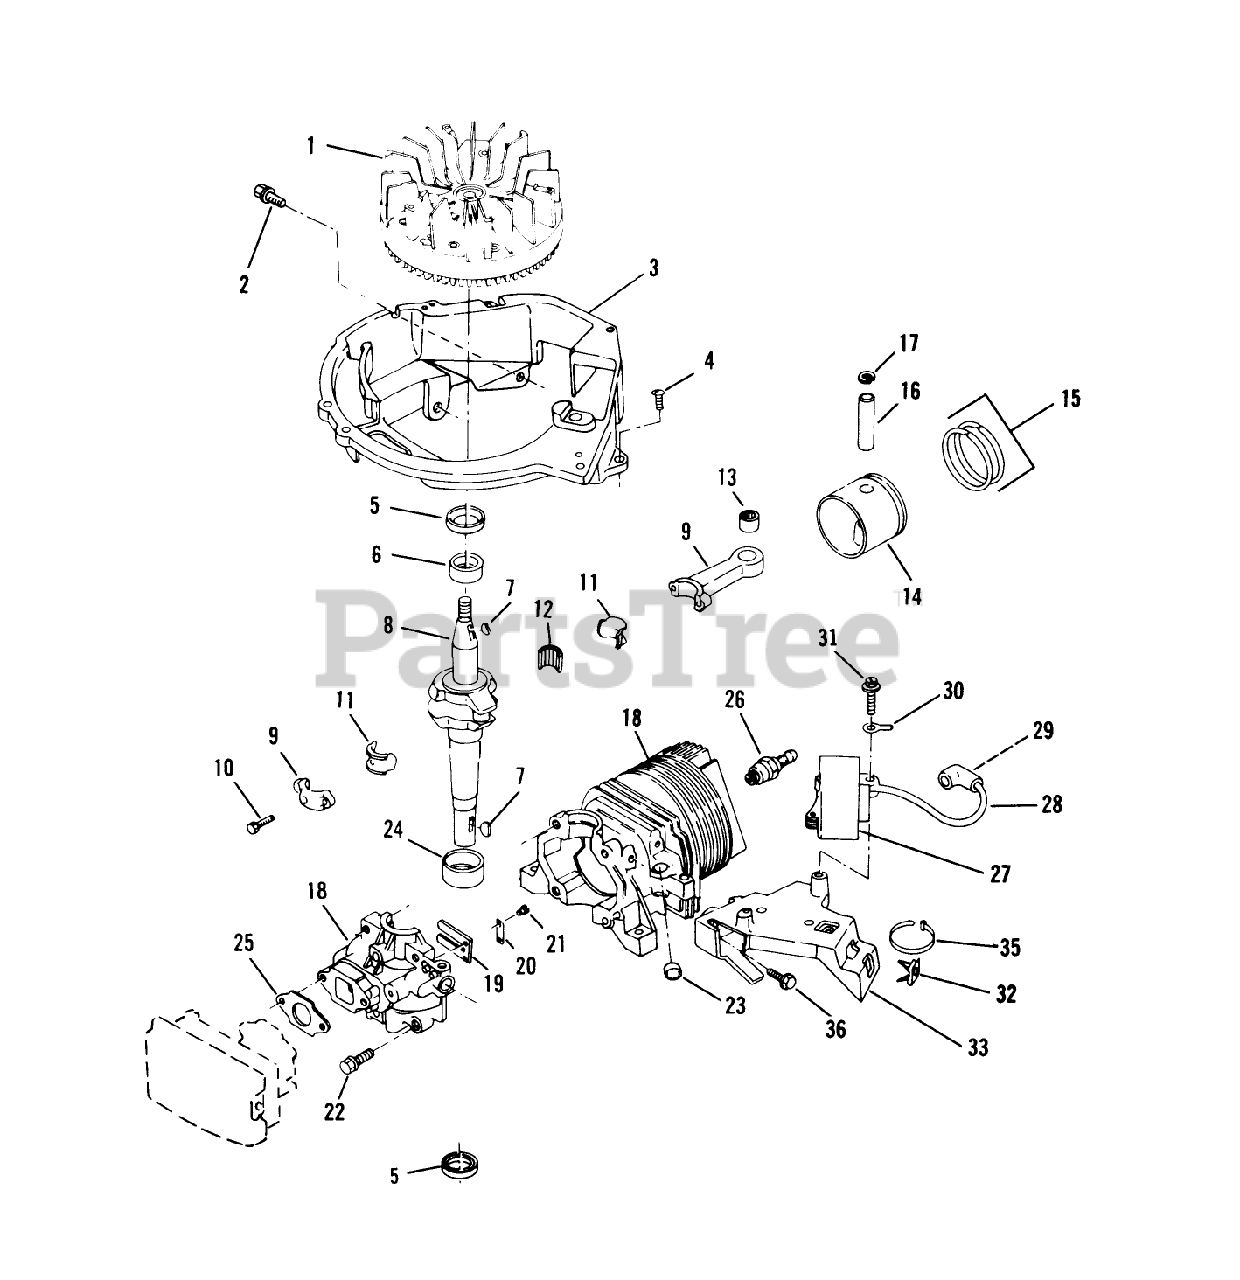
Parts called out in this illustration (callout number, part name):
2	SCREW-SEMS
4	SCREW F
5	SEAL-OIL
6	BEARING V
7	KEY
10	SCREW-HSH
11	LINER ASM
12	BEARING-NEEDLE
13	BEARING AY F
17	RING-RETAINING
20	PLATE-BACKUP, REED
21	SCREW-HH
22	SCREW S
23	PLUG-CORE VF
24	BEARING V
25	GASKET CARB S
28	HT LEAD&COVER XEV
30	TERMINAL S
32	NUT-CLIP
33	BRACKET S
